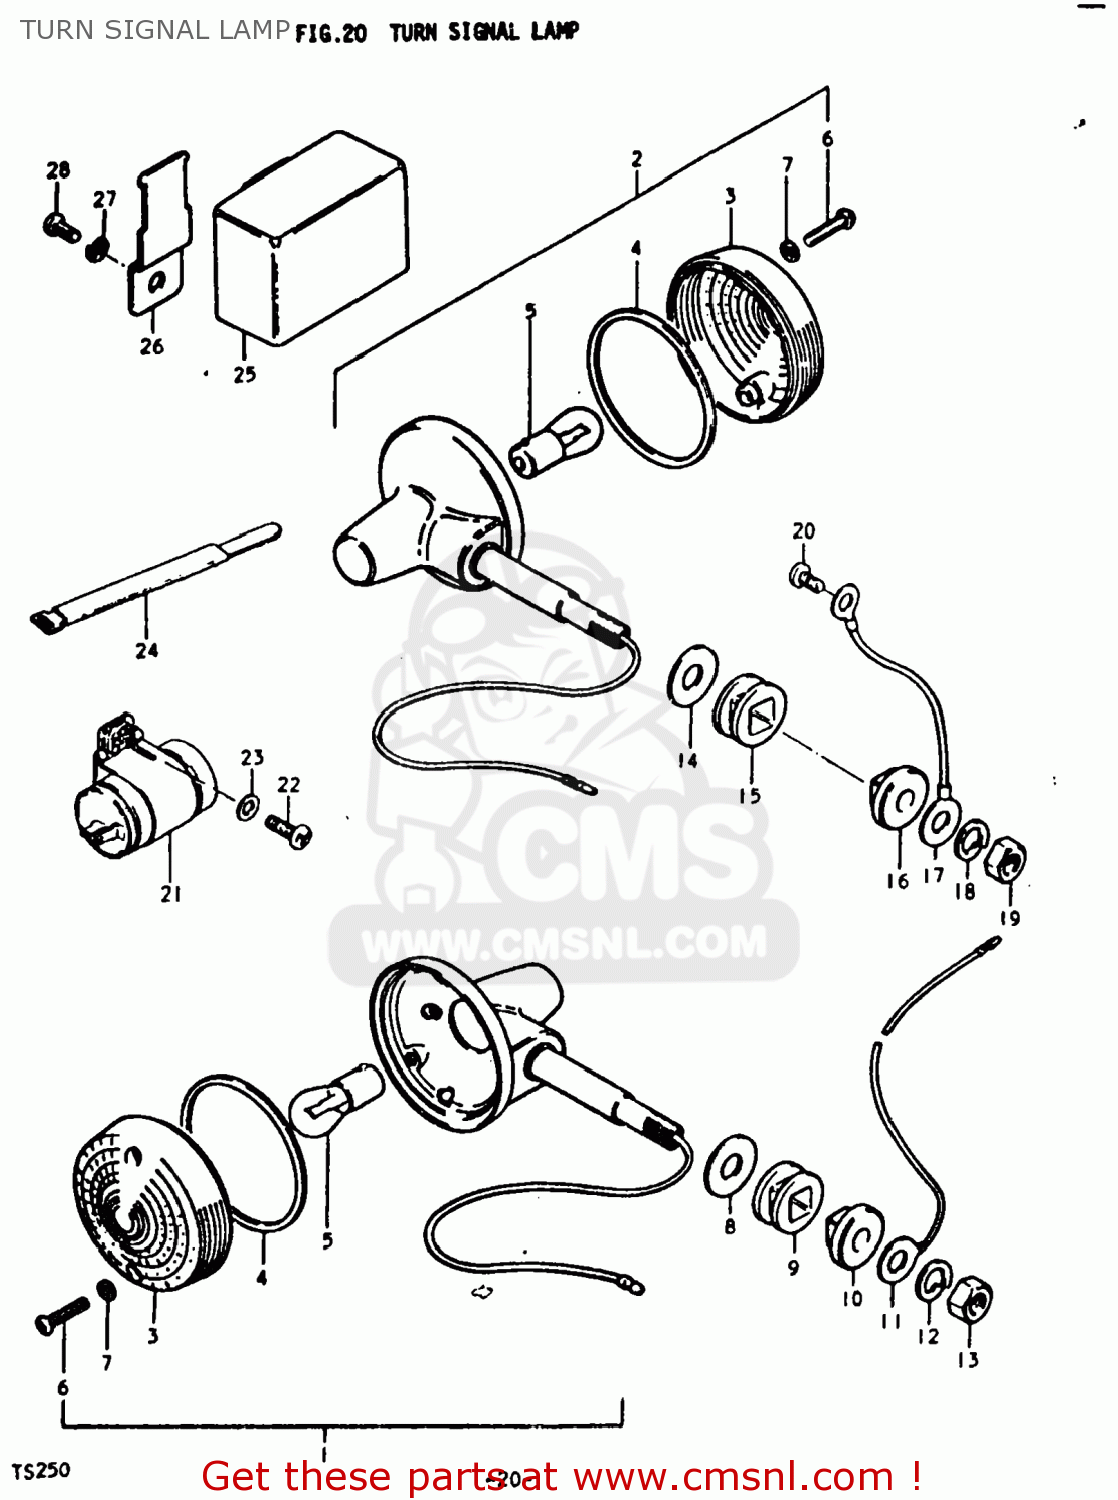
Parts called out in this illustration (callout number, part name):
1	LAMP ASSEMBLY,FRONT TURN SIGNAL
2	LAMP ASSEMBLY,REAR TURN SIGNAL
3	LENS
4	GASKET (NAS)
5	BULB(6V17W,STANLEY,A4513A)
6	SCREW
7	GASKET (NAS)
8	WASHER (10.5X30X2.3)
9	CUSHION
10	SPACER,RR TURNSIGNAL LAMP
11	LEAD WIRE,EARTH
12	LOCK WASHER
13	NUT
14	WASHER (10.5X30X2.3)
15	CUSHION
16	SPACER,RR TURNSIGNAL LAMP
17	LEAD WIRE
18	LOCK WASHER
19	NUT
20	SCREW
21	RELAY,TURN SIGNAL
22	SCREW
23	WASHER
24	CLAMP
25	RELAY,TURN SIGNAL
26	BRACKET,TURN SIGNAL RELAY
27	SCREW 6X12
28	LOCK WASHER
